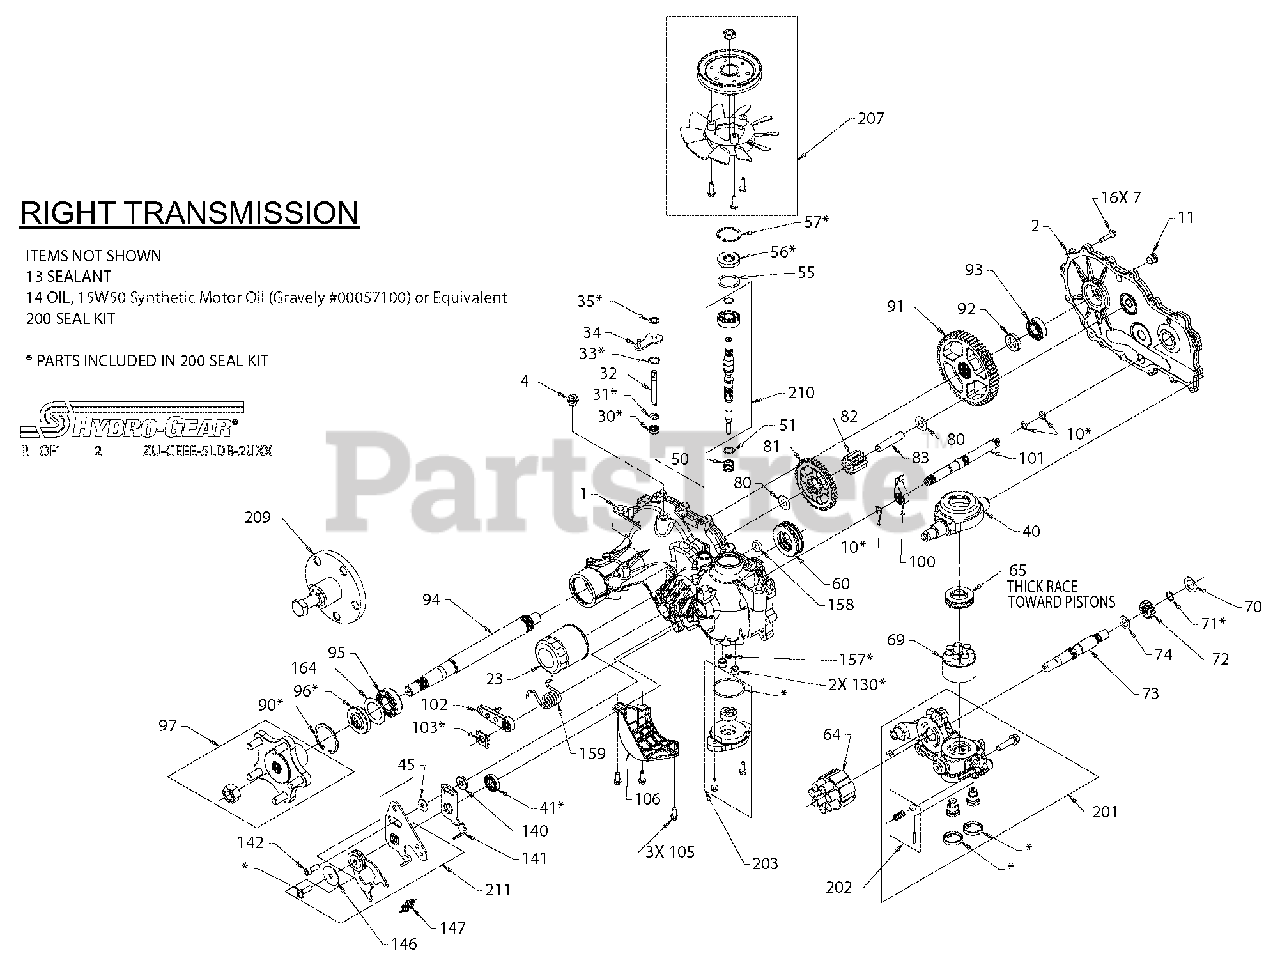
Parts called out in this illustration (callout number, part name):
7	HFHCS 1/4-20 X 1.25
13	SEALANT
23	FILTER, OIL
30	SEAL, LIP .375 X .75 X .25
31	RING, RET .375 EXTERNAL
33	RING, RET .750 INTERNAL
34	ARM, BYPASS
35	RING, RTNG .375 EXT
40	TRUNNION, SWASHPLATE
41	SEAL, LIP 18 X 32 X 7
45	WASHER .34 X .88 X .06
50	SPRING, BLOCK
51	WASHER-FLAT .59 x .79 x .04
55	WASHER 1.23 X 1.56 X .04
56	SEAL, LIP 17 X 40 X 7
57	RING, RET 2.06 INT
60	BEARING, THRUST
64	ASS'Y, CYLINDER BLOCK, 16cc
65	BRG, THRUST BALL 30 X 52 X 13
69	ASS'Y, BLOCK, 7 PISTON
70	WASHER .63 X 1.00 X .05
71	RING, RET .62 EXT
74	WASHER .72 X 1.16 X .04
80	WASHER .5 X 1.0 X .03
83	JACK SHAFT (PIN)
90	RING, RET 2.06 INT
95	BRG, BALL 1.0 x .52 x .15 OPEN 6205M
96	SEAL, LIP TC4 1.0 x 2.06 x .38
97	KIT, HUB, 5 BOLT
102	KIT, HANDLE ACTUATING
103	CLIP, RETAINING
105	SCREW, HEX FLANGE
106	GUARD, FILTER, RH
140	SPACER .320 x 1.005 x .179
141	ARM, NEUTRAL RIGHT
142	SHCS 5/16-24 x 1.00 (PATCH)
146	WASHER, .343 x 1.500 x .062
147	SPRING, EXTENSION RTN-34LBS
157	SEAL, LIP .281 x .420 x .16
158	MAGNET, RING
159	SPRING, TORSION CCW
200	KIT, SEAL
201	KIT, CENTER SECTION, RH, CHRG
203	KIT, CHARGE PUMP
